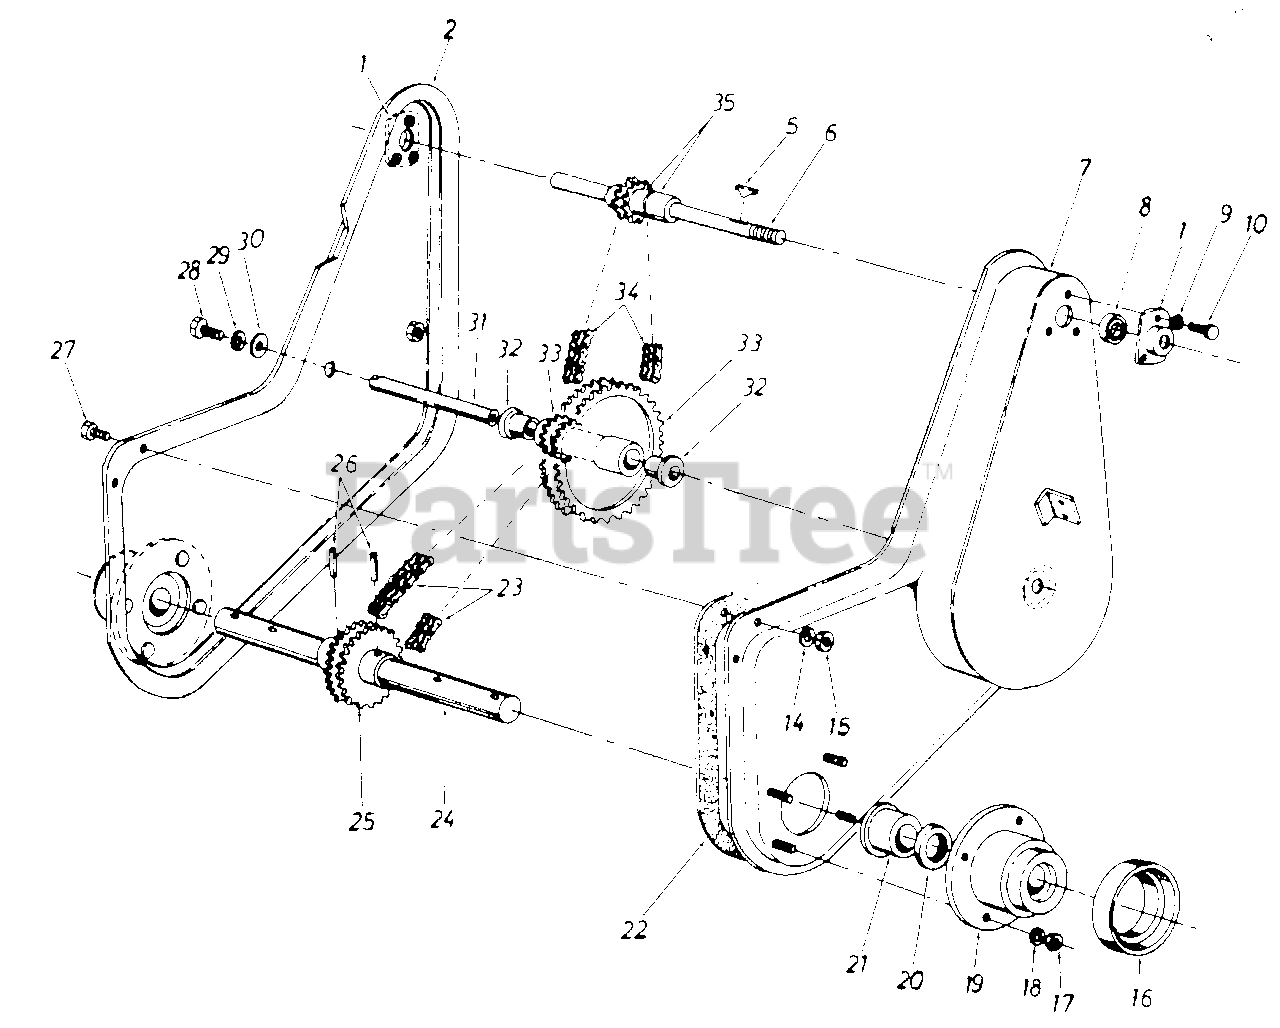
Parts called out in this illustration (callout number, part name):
1	Bearing Housing 1.375" Dia.
6	Input Shaft Assembly
9	L-Wash. 1/4" I.D.
10	Hex Bolt 1/4-20 x .62" Lg.
14	L-Wash. 1/4" l.D.
15	Hex Cent. L-Nut 1/4-20 Thd.
16	Dust Cap Cover
17	Hex Cent. L-Nut 5/16-18 Thd.
18	L-Wash. 5/16" I.D.
19	Cast Bearing Housing
20	Oil Seal
21	Flange Bearing 1.25" l.D. x 1.75" O.D.
22	Gasket
23	Roller Chain #40-2 x 34.0" Lg.
24	Tine Shaft
25	Double Sprocket T24-2 Teeth 1/2" Pitch
26	Spiral Pin 3/8" Dia. x 2.00" Lg.
27	Hex Bolt 1/4-20 x .62" Lg.
28	Hex Bolt 5/16-18 x .75" Lg.
29	L-Wash. 5/16" I.D.
30	Fl-Wash. 5/16" I.D.
31	Sprocket Shaft
32	Flange Bearing .62" I.D. x .75" 0 D
33	Double Sprocket Assembly
34	Roller Chain #35-2 x 36.75" Lg.
35	Spacer 5/8" I.D. x 7/8" O.D.
